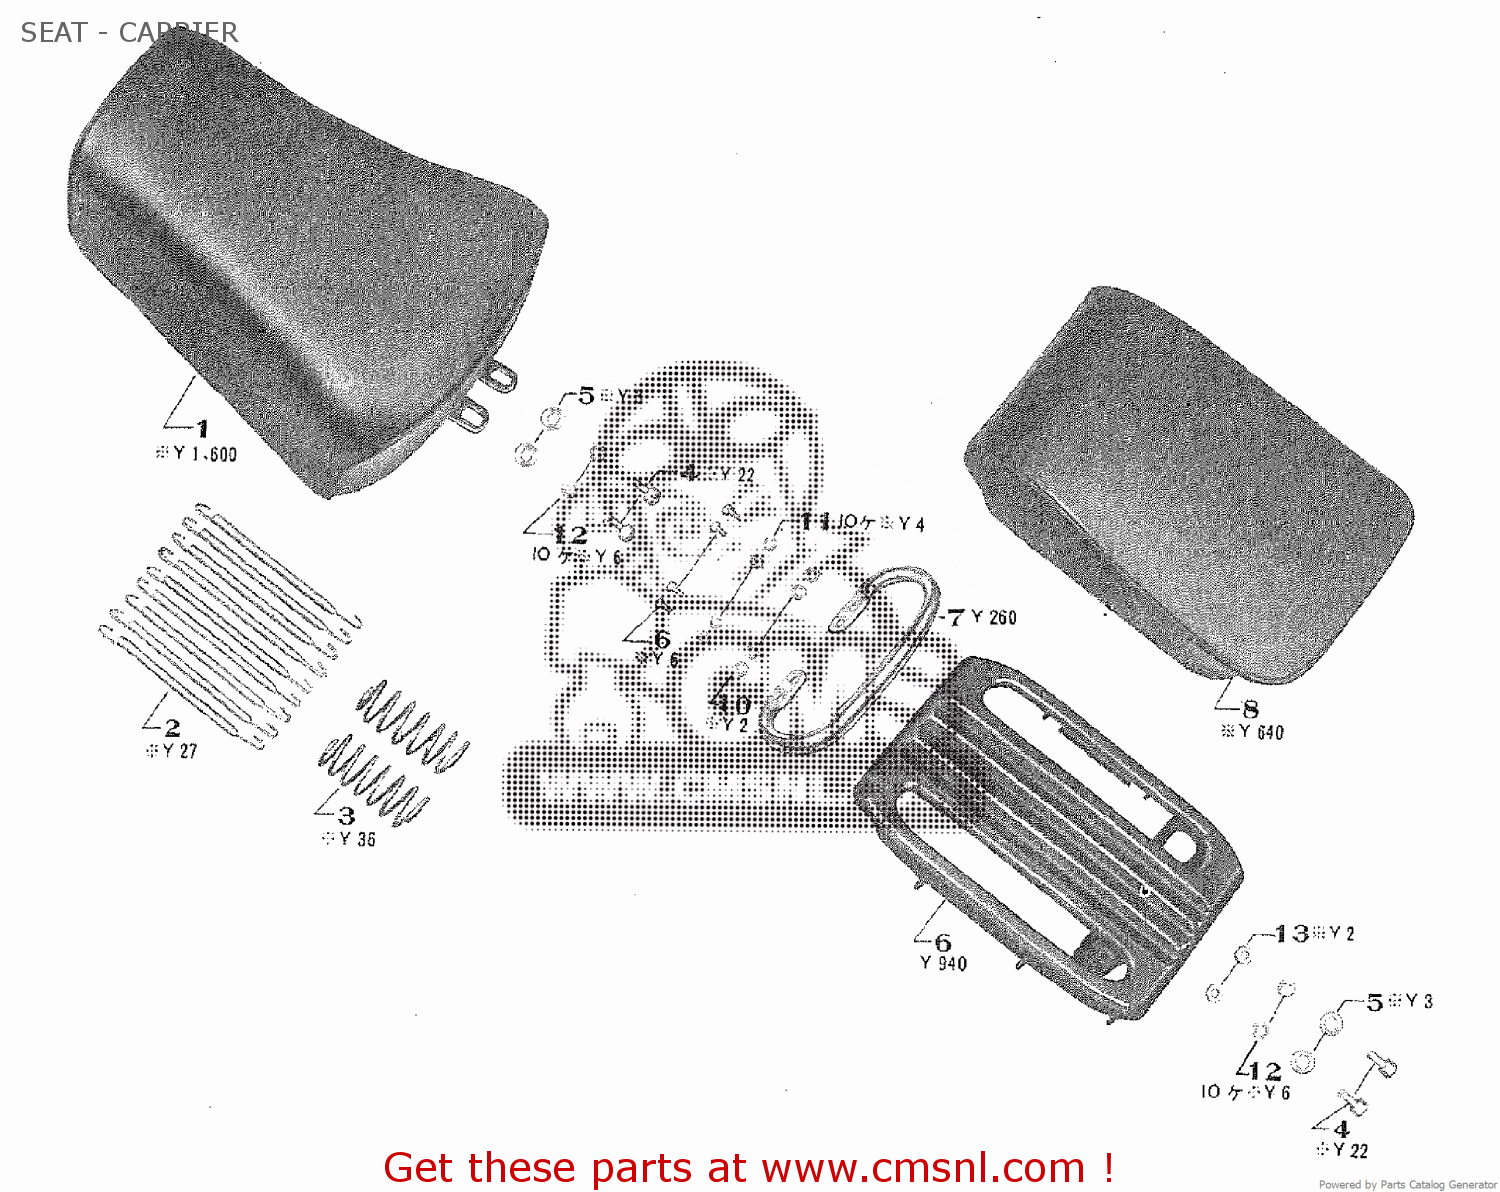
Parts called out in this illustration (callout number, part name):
1	SEAT ASSY.
2	TENSION SPRING
3	SEAT SPRING
4	SEAT SET BOLT
5	SET WASHER
6	CARRIER COMP.
7	CARRIER PIPE
8	TANDEM SEAT
9	6X12 HEXAGON BOLTAC
10	6MM PLANE WASHER
11	6MM SPRING WASHER
12	8MM SPRING WASHER
13	8MM HEXAGON NUT
